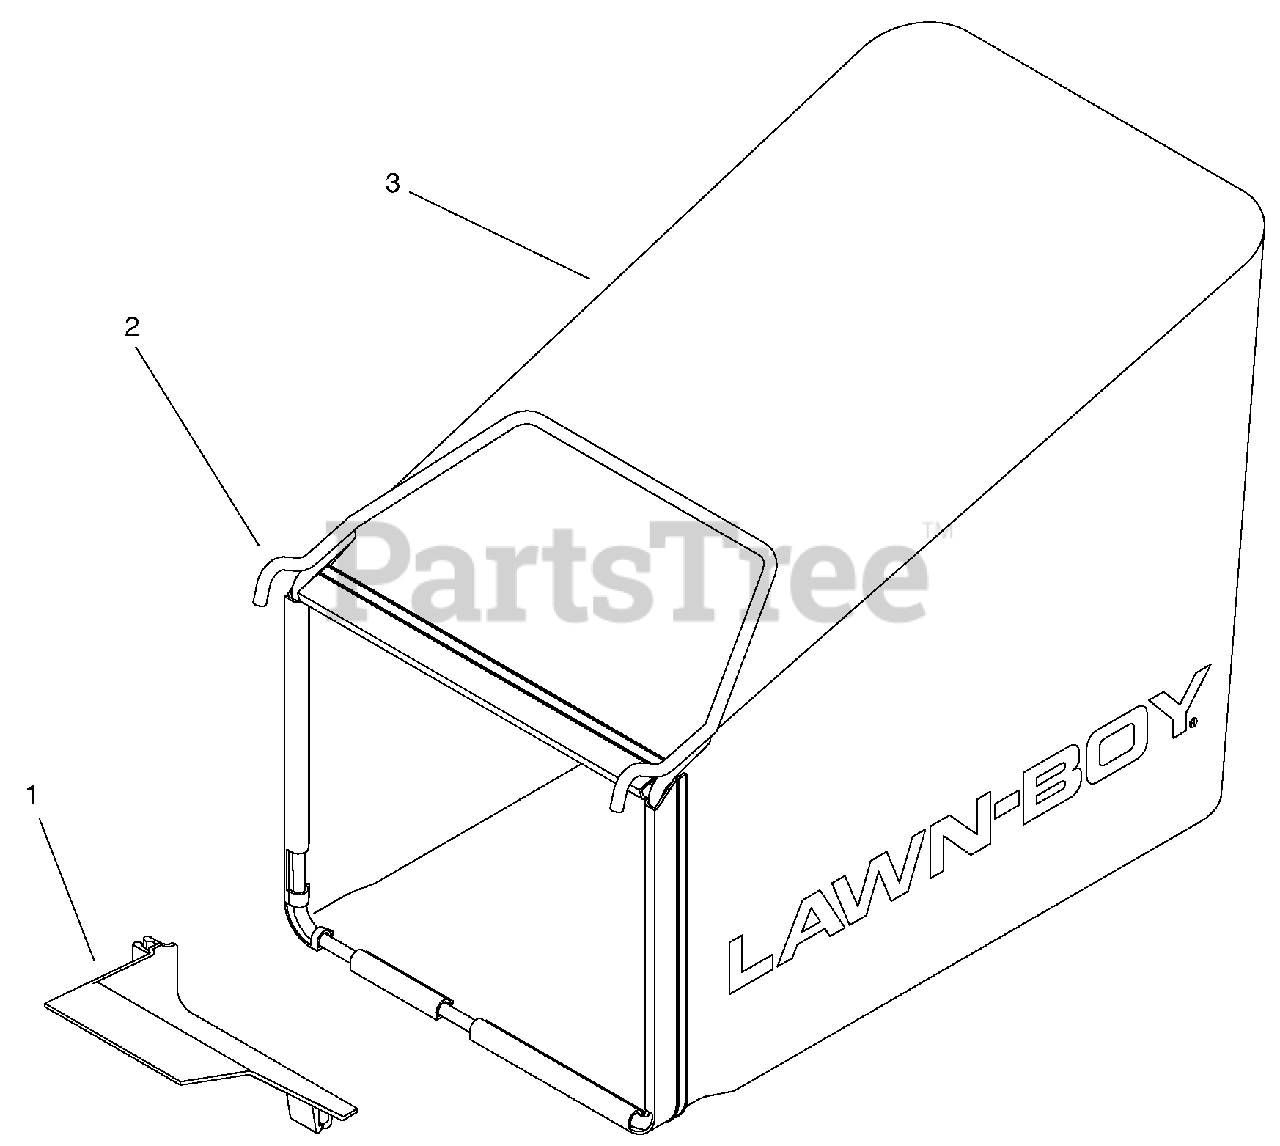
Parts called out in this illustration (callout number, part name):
1	Ramp-Grass Bag
2	Frame
3	Bag-Grass
